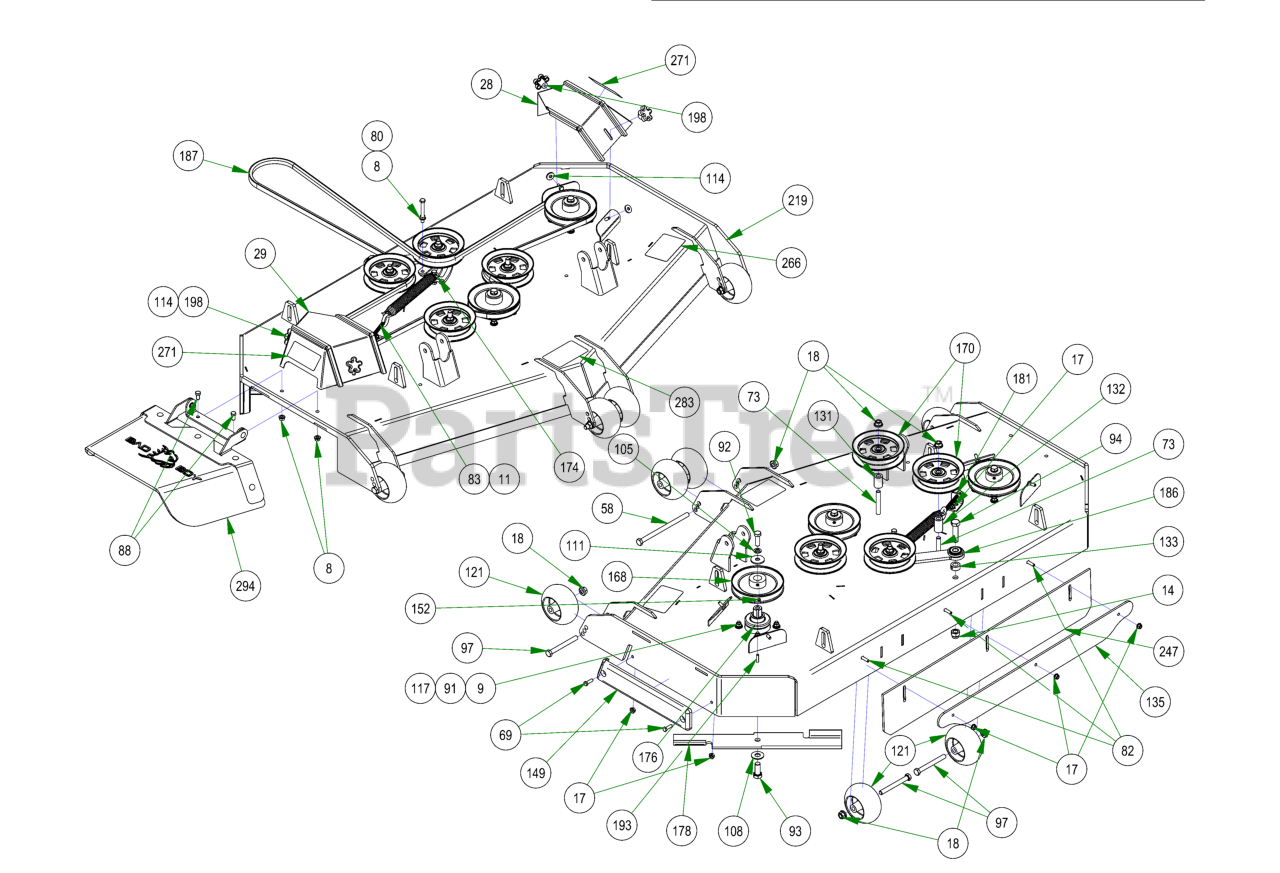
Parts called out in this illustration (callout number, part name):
8	3/8-16 HEX SERRATED FLANGE NUT HARD/ZINC
9	3/8-16 NYLON INSERT FLANGE LOCKNUT (GR.F) ZINC
11	3/8-16 HEX NUT ZINC
14	5/8-11 NYLON INSERT LOCKNUT ZINC
17	5/16-18 NYLON INSERT FLANGE LOCKNUT ZINC
18	1/2-13 NYLON INSERT FLANGE LOCKNUT ZINC
28	2019 61" Outlaw Gen2 Pulley Cover Left
29	2019 61" Outlaw Gen2 Pulley Cover Right
58	1/2-13 X 8 HEX CAP SCREW GR 5 ZINC
69	5/16-18 X 1 HEX CAP SCREW (GR.5) ZINC
73	1/2-13 X 3-1/2 HEX FLANGE BOLT (GR.8) ZINC
80	3/8-16 X 3 HEX CAP SCREW (GR.5) ZINC
82	5/16-18 X 1-1/4 CARRIAGE BOLT ZINC
83	4" 3/8-16 Eye Bolt
88	3/8-16 X 3/4 HEX CAP SCREW (GR.5) ZINC
91	3/8-16 X 1-1/2 HEX CAP SCREW (GR.5) ZINC
92	1/2-20 X 1-1/2 HEX CAP SCREW (GR.5) ZINC
93	5/8-18 X 1-1/2 HEX CAP SCREW (GR.8) ZINC YELLOW
94	5/8-11 X 2-1/2 HEX CAP SCREW (GR.5) ZINC
97	1/2-13 X 4-1/2 HEX CAP SCREW (GR.5) ZINC
101	5/16-18 X 7/8 CARRIAGE BOLT ZINC
105	1/2 SPLIT LOCKWASHER (GR.8) ZINC/YELLOW
108	5/8 USS FLAT WASHER (1-3/4" OD) GR.8 ZINC YELLOW
111	1/2 BELLEVILLE WASHER (1-5/8 OD X .140 THK) ZINC
114	.360 ID X .983 OD X .120 THICK FLAT WASHER NYLON
117	5/16 USS FLAT WASHER (7/8 OD) ZINC
121	2019 Deck Wheel
131	.502 ID X .750 OD X 1.500 Long Spacer
132	1 3/4" Pulley Spacer
133	5/8 SOLID SHAFT COLLAR (W/1 SET SCREW) ZINC
135	61 Bolt in Baffle Deck v2 Stripping Plate
149	REVISED TRIM BUMPER_20180226
152	5/16-24 X 1/4 SOCKET SET SCREW (CUP PT) PLAIN
168	6 1/4" Drive Pulley
170	5-3/4 Idler Pulley
174	2019 Outlaw Gen2 Deck Spring
176	OUTLAW SPINDLE ASSEMBLY
178	61 inch Fusion Blade
181	2019 Deck Eye Bolt Tab
186	2019 Rebel Rogue Deck Idler
193	1/4 X 1 SQ MACHINERY KEY 1018 STL PLN
198	5/16" Knob
219	2019 Sloped 61" Deck
247	R Series Rubber For Deck
266	2018 61" Deck Decal
271	Danger Decal-Spindle/Discharge
283	2019 Rebel & Rogue Deck Belt Route Decal
294	2019 Outlaw Gen2 Chute Assembly
